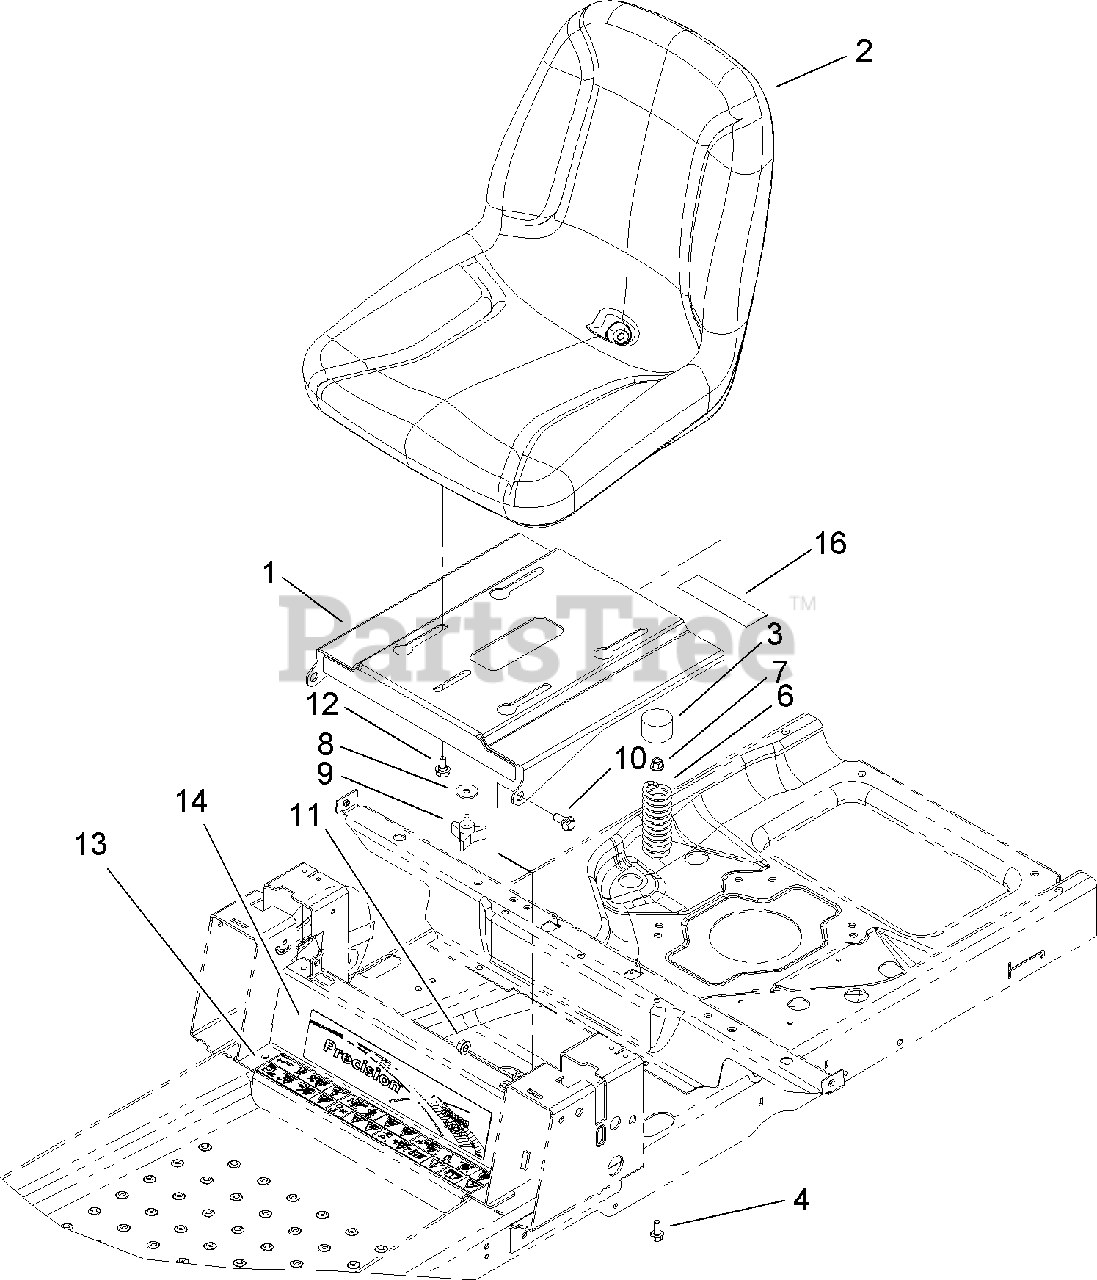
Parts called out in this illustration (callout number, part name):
1	BASE-SEAT
2	SEAT-18 INCH
3	CAP-PROTECTOR
4	SCREW-HHF
6	SPRING-COMPRESSION
7	NUT-LOCK, NI
8	WASHER-PIVOT
10	BOLT-SHOULDER
12	BOLT-SHOULDER
13	DECAL-DANGER
16	DECAL-SERVICE
